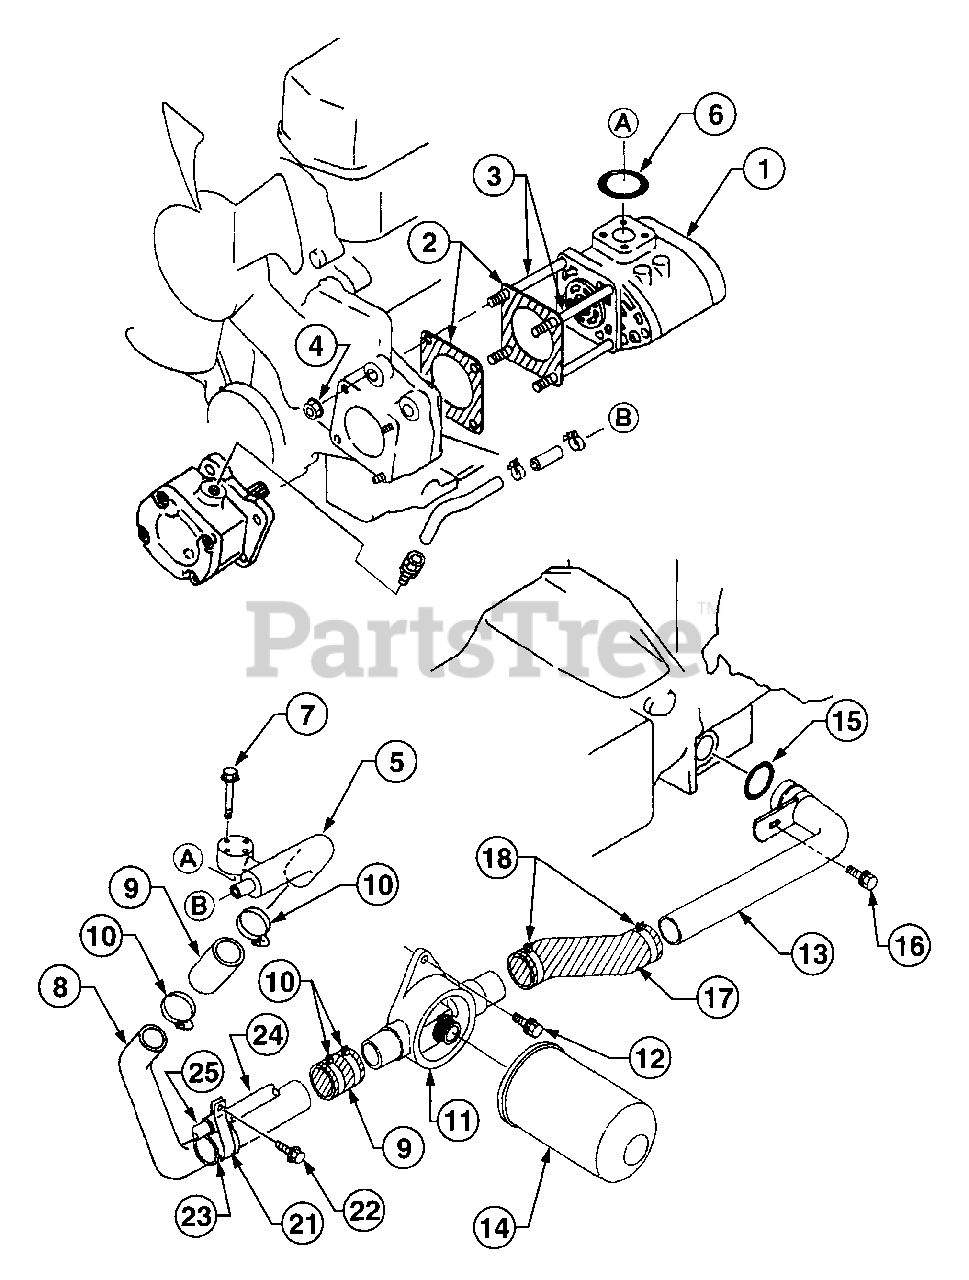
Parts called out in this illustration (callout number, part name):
5	Pipe Suction D
7	Bolt, w/Washer
8	Pipe Suction B
12	Bolt, w/Washer
13	Pipe Suction C
